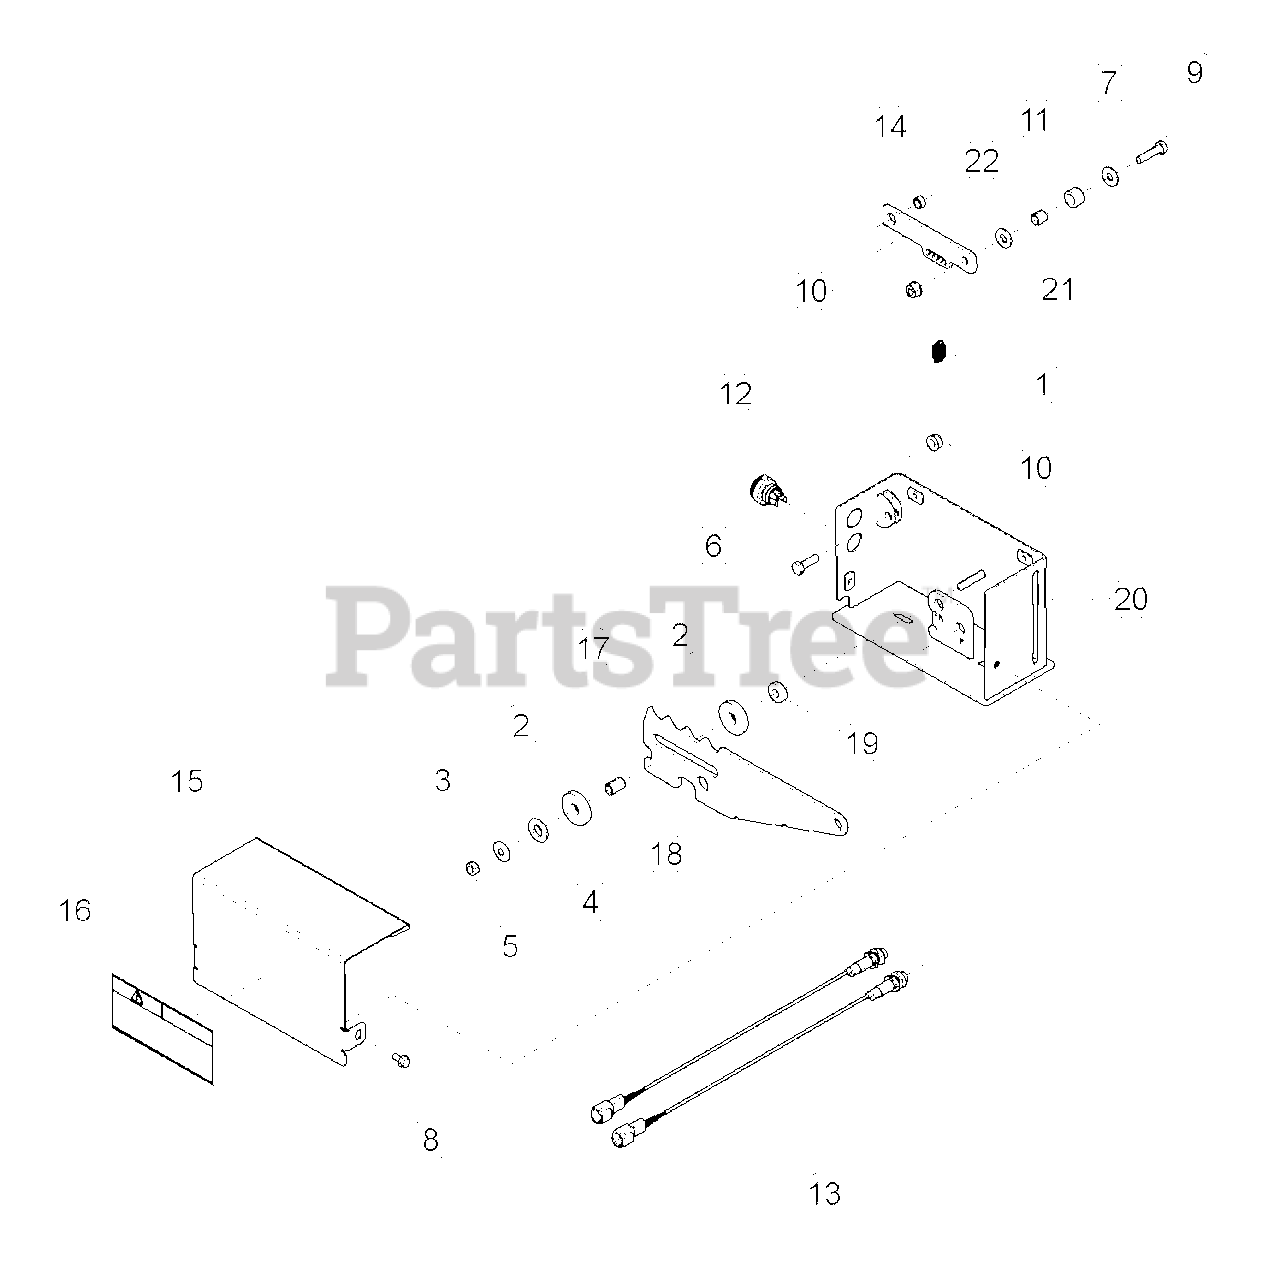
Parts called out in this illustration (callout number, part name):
1	SPRING, CONTROL BAR
2	WASHER, UHMW SPACER .515ID-1.50OD
3	WASHER, SPRING
4	WASHER, 1/2 SAE FLAT ZP
5	NUT, 5/16 CENTERLOCK NC ZP
6	BOLT, 5/16 X 1 HEX GR5 NC ZP
7	WASHER, 5/16 FLAT ZP
8	BOLT, 1/4 X 1/2 SERRATED FLANGE GR5 ZP
9	BOLT, 5/16 X 1-1/4 HEX GR5 NC ZP
10	NUT, 5/16-18 NYLOCK-FLANGE
11	ROLLER, NYLON .75OD X .502ID X .440
12	LIGHT, LED TRI-COLOR
13	SENSOR, M12 PNP PROXIMITY (REPLACEMENT PART)
14	SPACER, IDLER PIVOT
15	ASSEMBLY, CONTROL COVER W/ DECAL
16	DECAL, MULTILINGUAL MANUAL
17	BAR, SWITCH CONTROL
18	SPACER, .50 X .728
19	SPACER, .375" X .25"
20	WELDMENT, SWITCH BOX
21	LINK, DETENT
22	SPACER, 1/2 OD X .35 ID X .47
